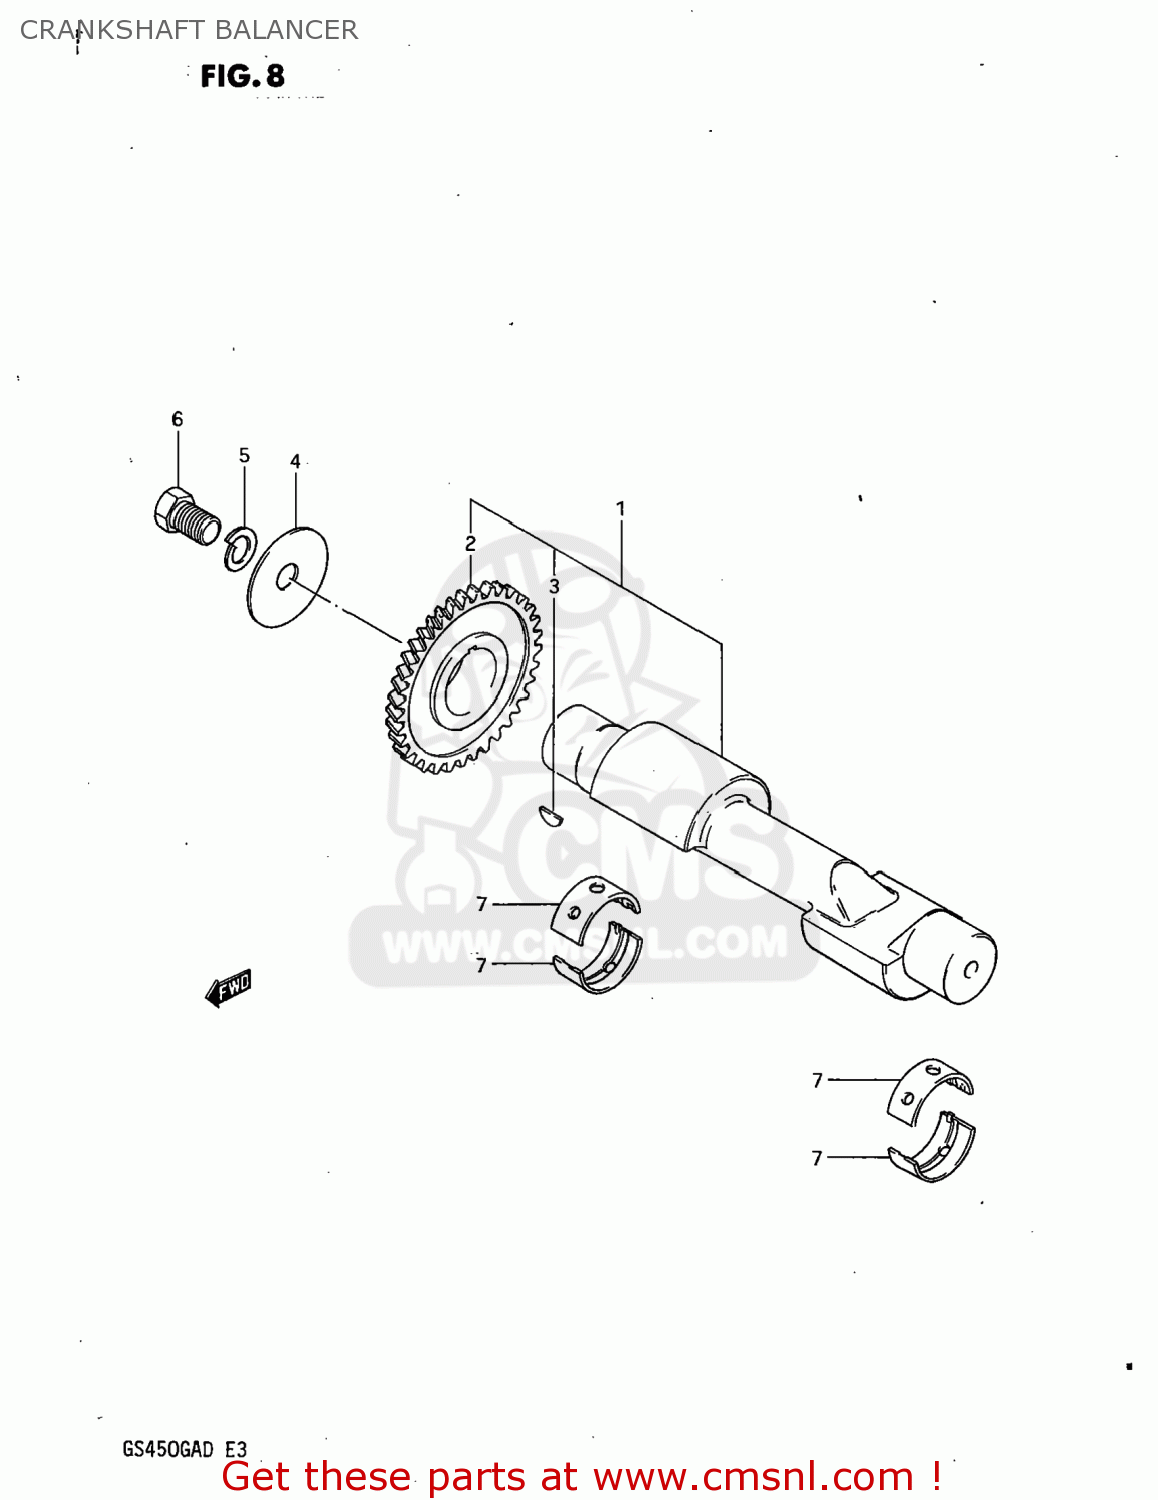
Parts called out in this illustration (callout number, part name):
1	BALANCER,CRANKSHAFT
2	GEAR,CRANK BALANCER
3	KEY 4MM
4	WASHER(12X50X3)
5	WASHER,LOCK 12
6	BOLT
7	METAL CRANKSHAFT
